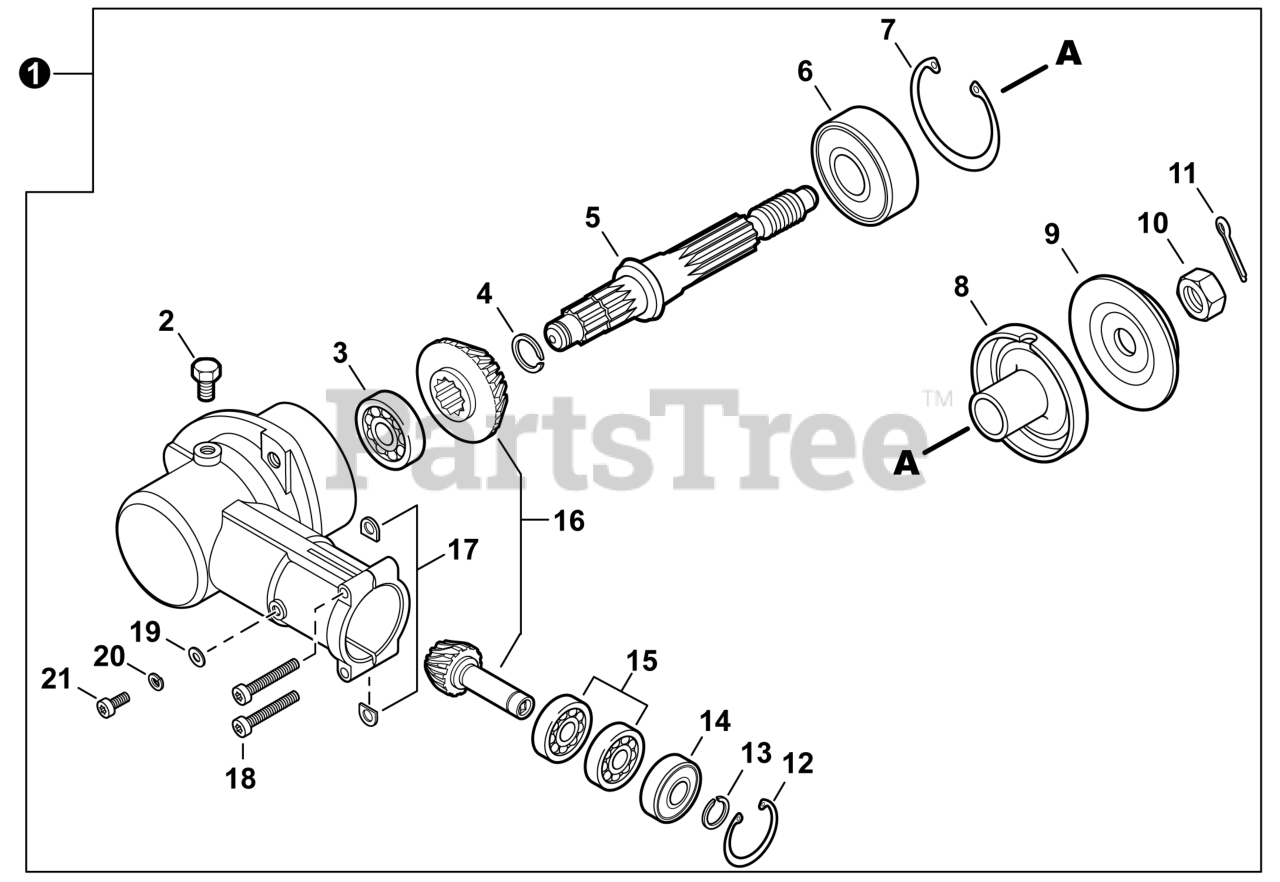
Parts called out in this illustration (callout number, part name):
1	GEAR CASE ASSY
2	BOLT M8x8
3	BEARING, BALL 629
4	RING, SNAP 12
5	SHAFT, GEAR
6	BEARING, BALL 6302
7	RING, SNAP 42
8	PLATE, ADAPTOR - UPPER
9	PLATE, ADAPTOR - LOWER
10	NUT 10x1.25 LH
11	PIN, COTTER 2x22
12	RING, SNAP 22
13	RING, SNAP 10
14	BEARING, BALL 6900Z
15	BEARING, BALL 6900
16	GEAR SET
17	D-WASHER
18	BOLT, TORX 5x25
19	WASHER, FLAT 5.5x10x0.8
20	WASHER, SPRING 5
21	BOLT, TORX 5x12
